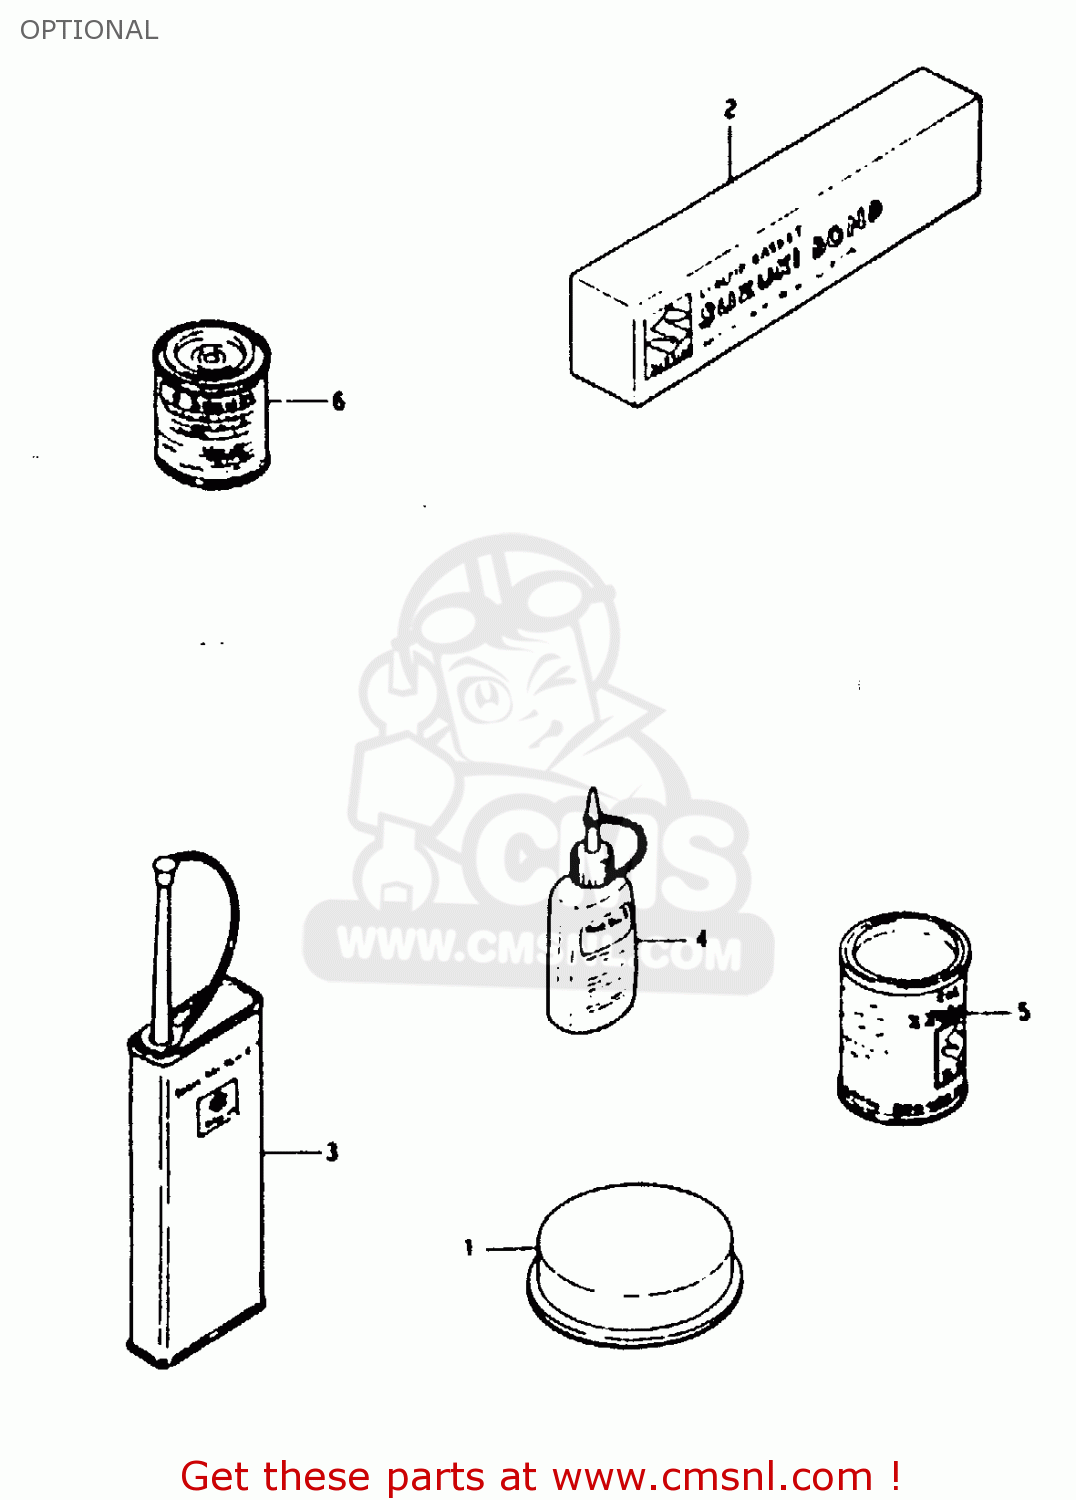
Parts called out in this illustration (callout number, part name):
1	GREASE,PBC FOR BRK PAD 20G
2	BOND 1104
3	THREAD LOCK NO.1401 CLEAR 200G
4	THREAD LOCK SUPER(1360)
5	GREASE(C)EP2 LITHIUM 150G
6	PAINT,BLACK
